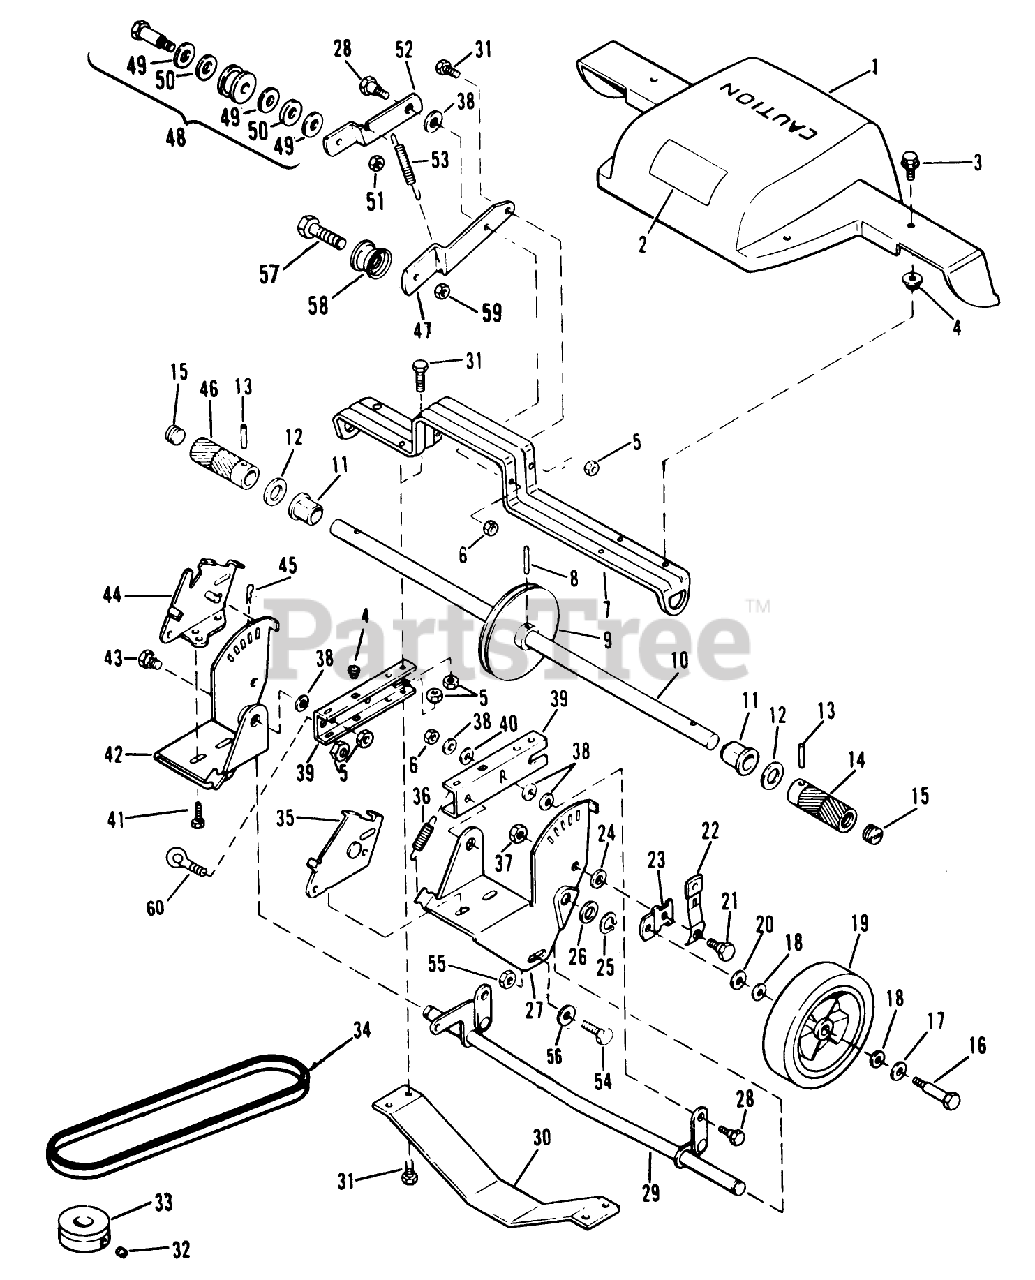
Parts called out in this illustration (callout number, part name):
1	COVER & DECAL AY
5	LOCKNUT E
6	STOP NUT
8	ROLL PIN
9	PULLEY
11	SLEEVE &BEARING AY
13	PIN
15	GREASE PLUG
16	BOLT WHEEL
17	SPACER
18	WASHER
19	WHEEL & TIRE KIT
20	WASHER WROUGHT
21	BOLT
22	KNOB & SPRING
24	WASHER
25	RET RING
28	BOLT RB&W
32	SET SCREW F
33	PULLEY F
34	V-BELT
36	SPRING
37	LOCKNUT
38	WASHER S
41	SCREW
43	BOLT RB&W
45	HAIR PIN
46	R.H. DRIVE ROLLER
49	THRUST WASHER
51	NUT-LOCK F
55	NUT-LOCK F
58	PULLEY IDLER NHI
59	LOCKNUT
60	BOLT-EYE
